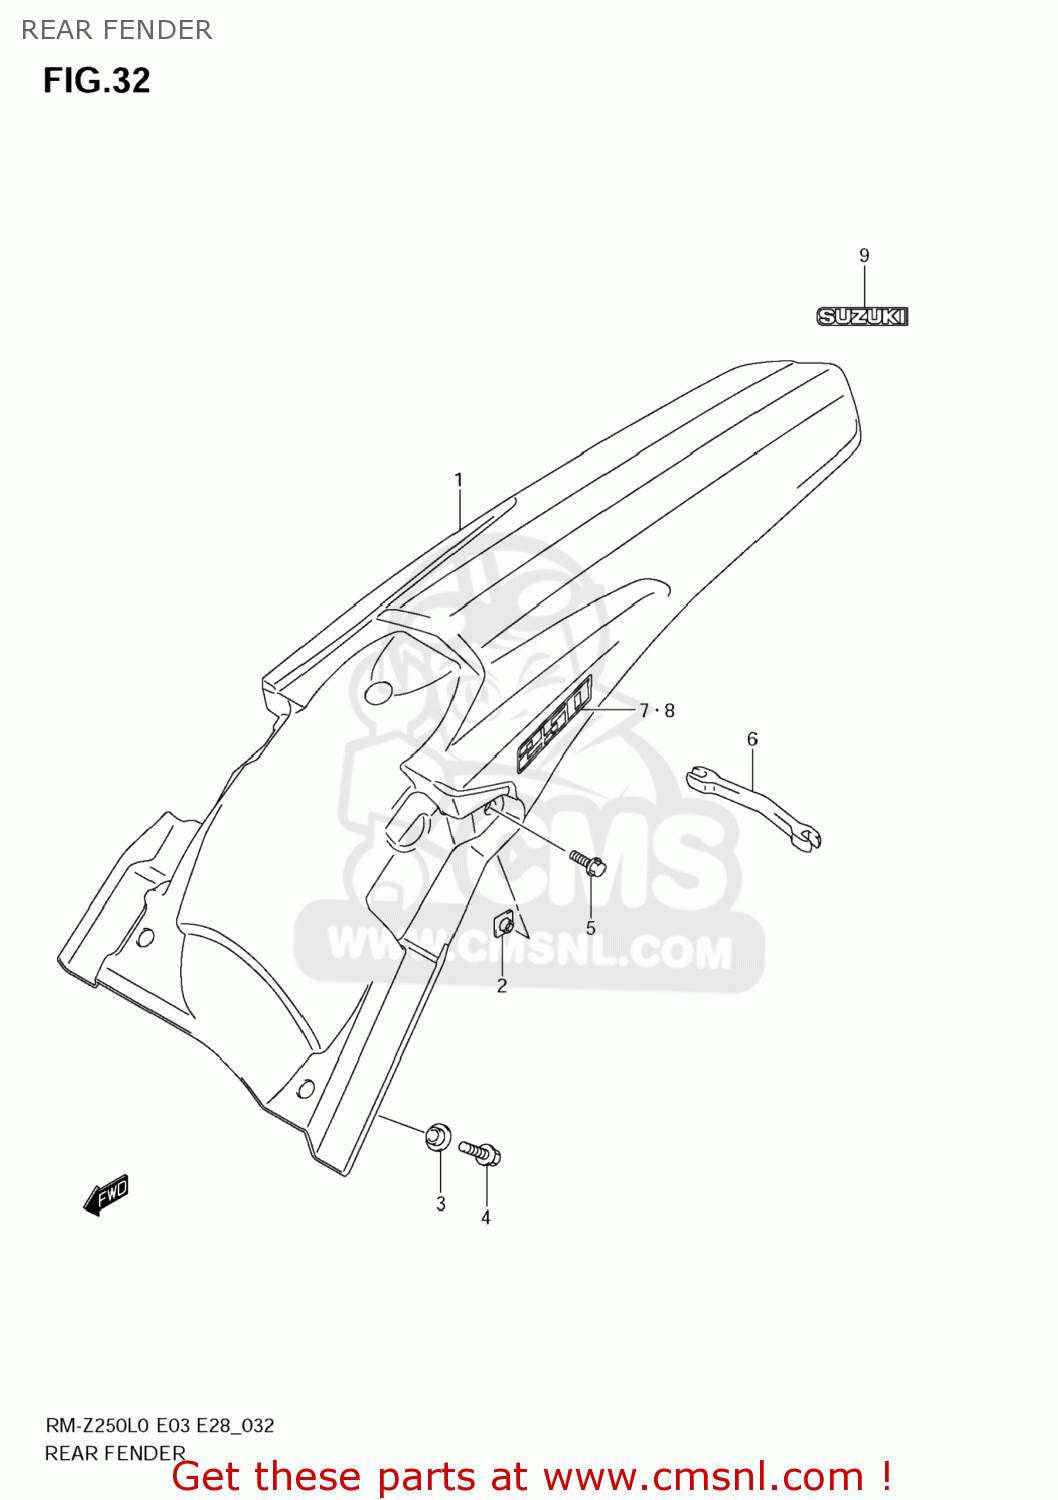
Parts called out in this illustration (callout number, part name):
1	FENDER,REAR
2	NUT
3	WASHER,FR FENDER
4	BOLT,6X20
5	BOLT(6X16)
6	OPEN SPANNER(6.4X6.8)
7	EMBLEM,RR FENDER,R
8	EMBLEM,RR FENDER,L
9	EMBLEM,SUZUKI
